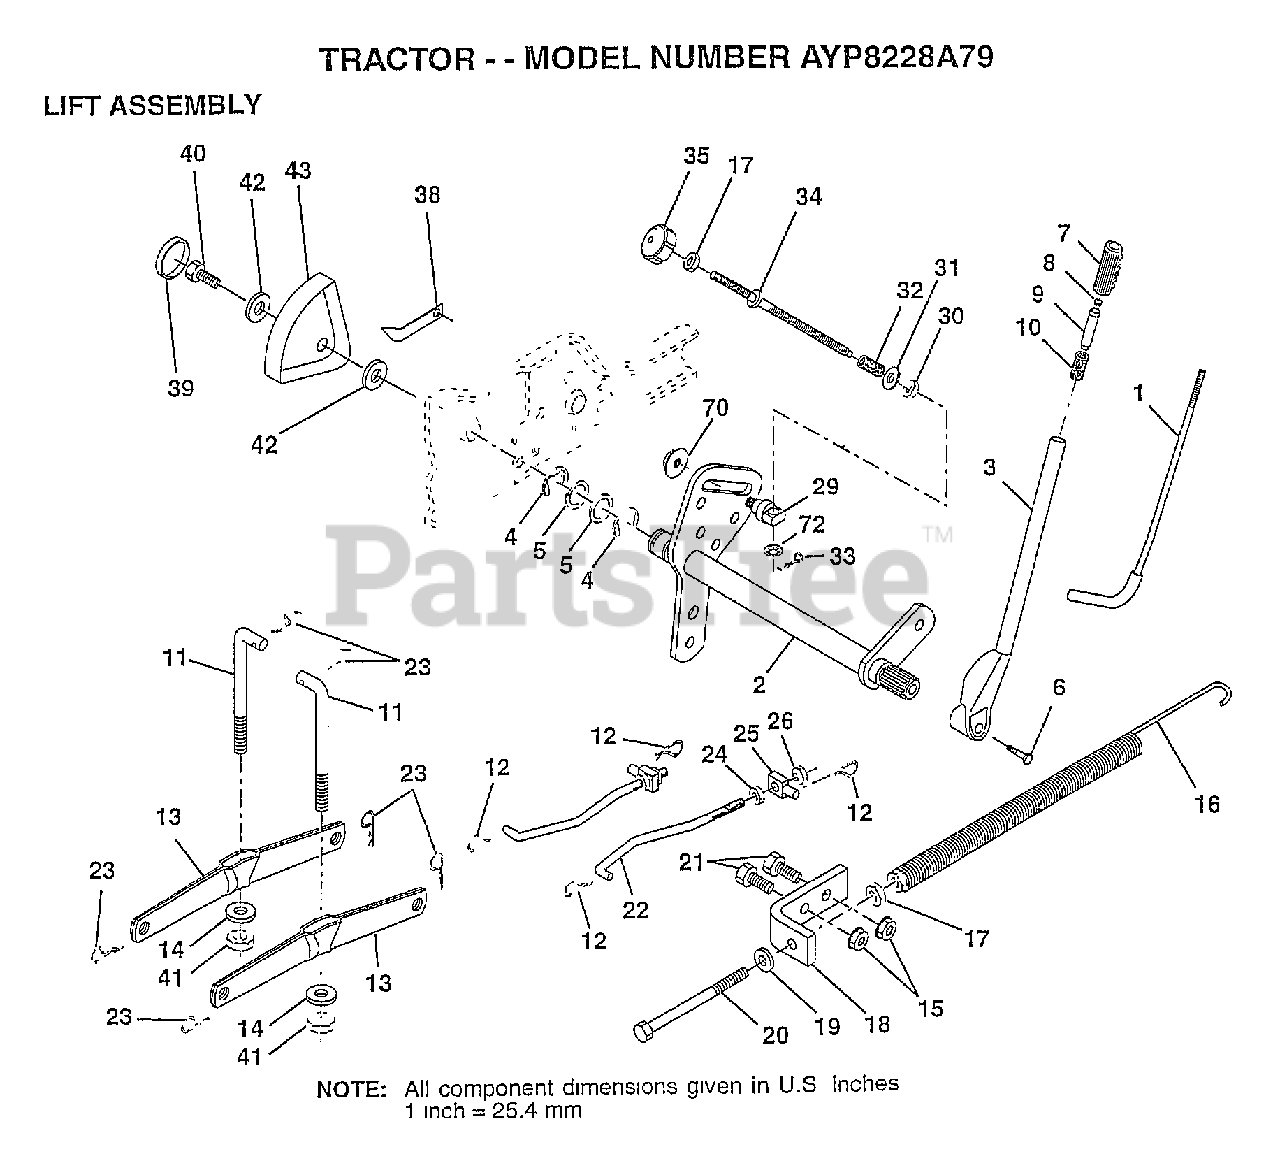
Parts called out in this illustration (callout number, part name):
1	LEVER ROD LT
2	SHAFT AMS LIFT
4	E-RING
5	WASHER
6	"BOLT,HEX"
7	GRIP HANDLE
10	SPRING T
11	LINK.LIFT.MWR.VGT
12	RETAINER.SPRING
13	ARM SUSP REAR
14	BEARING PVT LH
17	NUT
18	BRACKET SPRING AS
19	WASHER
20	BOLT-ADJ SPRING T
21	BOLT
22	LINK.FRONT
24	NUT
25	TRUNION
26	NUT.LK.W/WSH.1/2.
29	TRUNNION
30	NUT T
31	WASHER
32	SPRING.COMP.INF.H
34	ROD.ADJ.LIFT
35	KNOB INF 3/8-16
38	POINTER-INDICAT
39	"PLUG,HOLE"
40	SCREW
41	NUT.CROWNLOCK.3/8
42	WASHER
43	HEIGHT INDICATOR
70	NUT.HXFLG.LOCK.
72	NUT PUSH M
